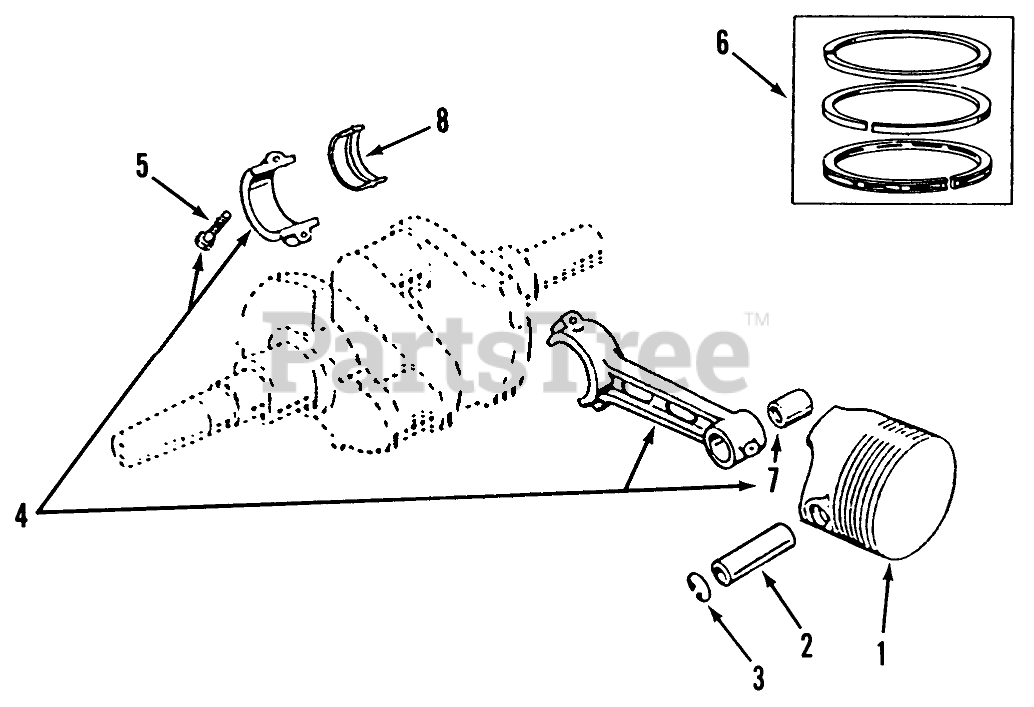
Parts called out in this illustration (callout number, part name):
1	Piston and Pin (includes Pin and Retaining Ring)
2	Piston Pin
3	Retaining Ring
4	Connecting Rod (Includes Bolts)
5	Rod Cap Bolt
6	Piston Ring Set:
7	Piston Pin Bushing
8	Connecting Rod Bearing Half:
